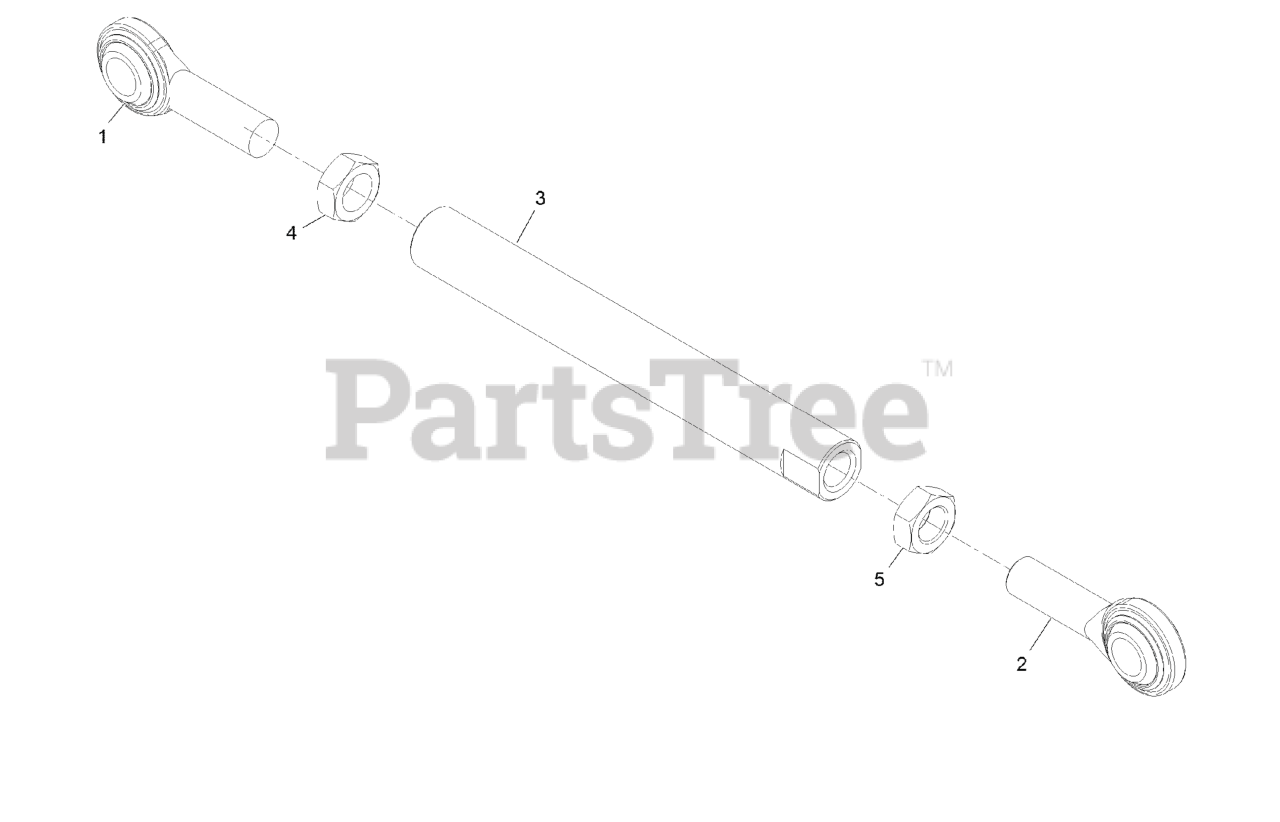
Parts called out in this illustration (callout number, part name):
1	BALLJOINT-SPHERICAL
2	BALLJOINT-SPHERICAL
3	ROD, LIFT
4	NUT-JAM
5	NUT-JAM
